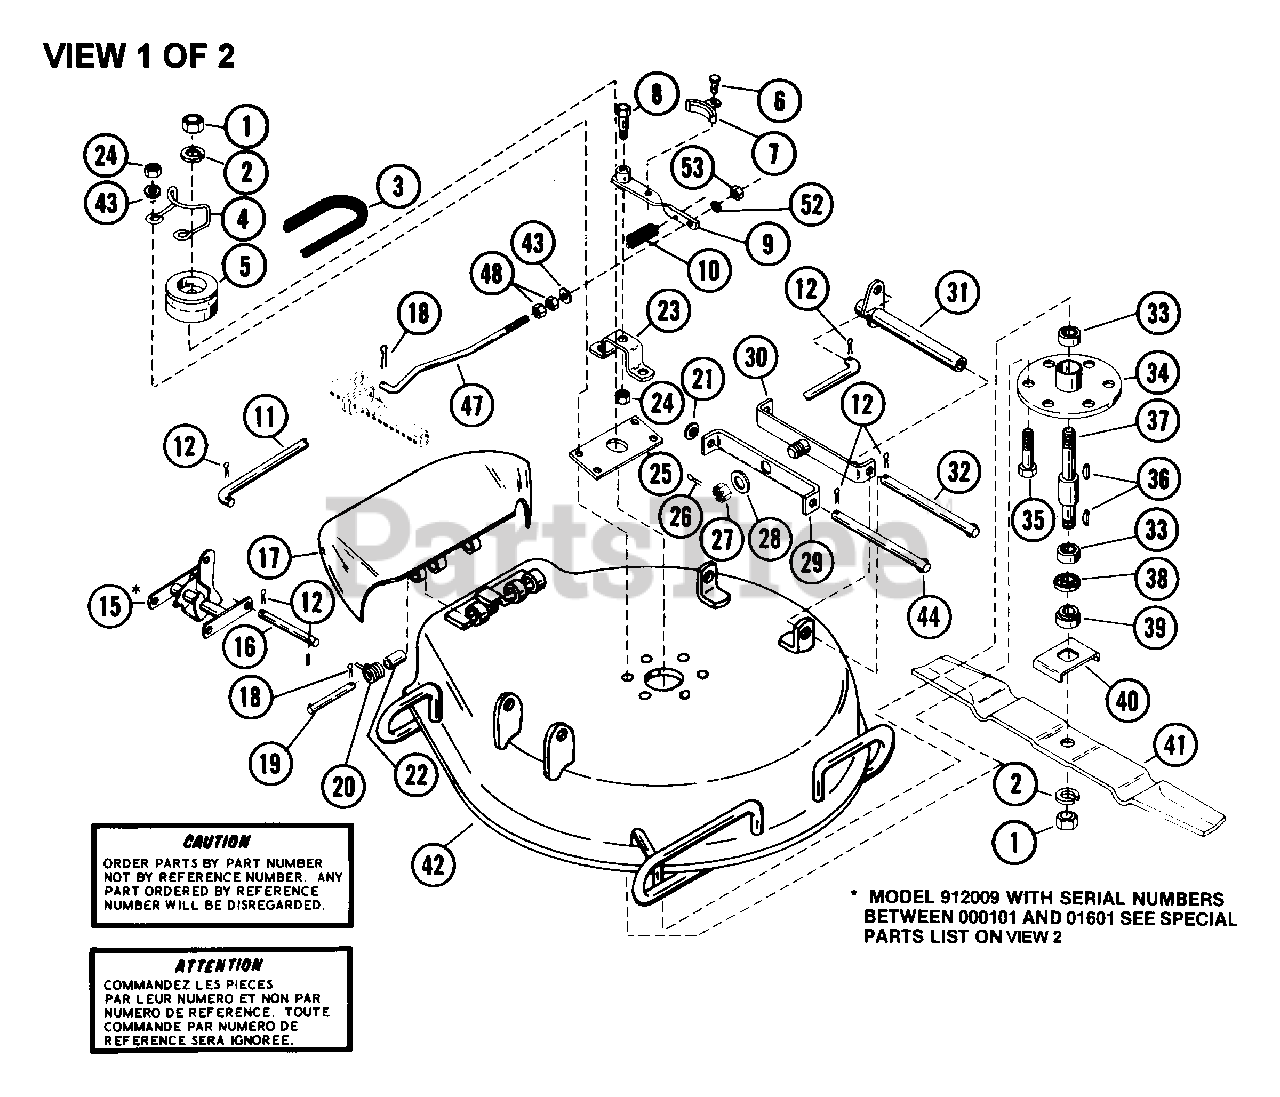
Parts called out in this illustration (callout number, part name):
1	NUT-JAM .75-10 PL
2	WSHR-LK .750X.188 MED PL
3	V-BELT, 5L-RAW EDGE
4	MOWER BELT FINGER
5	MOWER SHEAVE
6	RVT .25X.50 RH ST
7	BLADE BRAKE
8	SHOULDER BOLT .50 X 1.75
9	BRAKE ARM
10	SG-TENS .072X.51X5.31 WLD 25
11	HEIGHT LINK ROD
12	PIN-COTR .12X1.0 PL
15	PAN HEIGHT BRACKET
16	ADAPTER PIN
17	PAN CHUTE EXTENSION
18	PIN-COTR .09X.75 PL
19	CLEVIS PIN
20	SG-TORS .095X.50X 1.0
21	WSHR-FL-STL .531X1.062X.095 PL
22	BSHG-SLV .334 X .502 X 1.437
23	BLADE BRAKE SUPPORT
24	NUT-LK-CTR .375-16 GR A PL
26	PIN-COTR .12 X 1.25 PL
27	NUT-JAM-SL .625-18
28	WSHR-FL-STL .630X1.005X.062 PL
31	REAR RAISING BRACKET
32	REAR BRACKET PIN
33	BRG-BALL .751X1.78X.61
34	SPINDLE HOUSING
35	BLT-HEX .38-16X1.00 PL
36	KEY-WDRF .188X.75X.313 SAE 9
37	MOWER SPINDLE
38	BEARING SLINGER
39	RETAINER HUB
40	BLADE TRAY
41	BLADE, MOWER
42	MOWER PAN ASSEMBLY
43	WSHR-FL-STL .38X.875X.083 PL
44	HANGER PIN
47	BLADE BRAKE ROD
48	NUT-HEX .312-18
52	GROMMET
53	NUT-LK .312-18 GR A PL
107	PAN HEIGHT BRACKET
